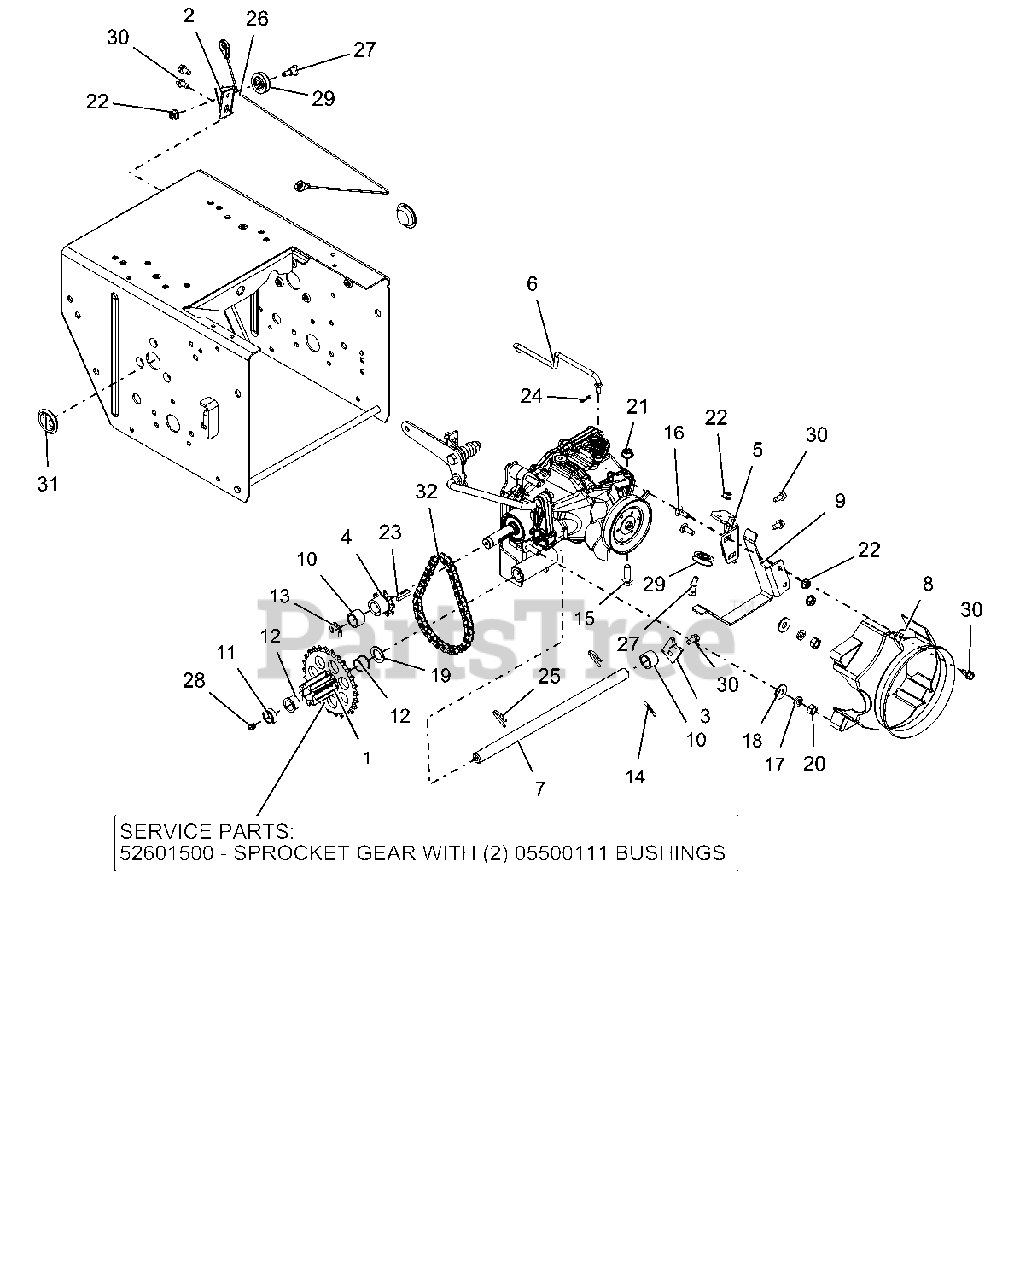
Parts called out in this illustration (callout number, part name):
1	BSHG-FLG .625X.750X.500X.875
1	PINION & SPROCKET
1	PINION & SPROCKET W/BUSHINGS
2	BRACKET, CABLE PULLEY
3	TAB, ANTI ROTATION
4	SPROCKET, PINION 9T W/KEY
5	BRACKET, CLUTCH CABLE
6	ROD, HYDRO BYPASS
7	SHAFT, PINION - HARDENED
8	SHROUD, HYDROGEAR RT-310
9	FINGER, BELT - FLAT
10	SPACER, .635X.880X.611
11	BSHG-SLV, .635X.880X.305
12	BSHG-FLG .625X.750X.500X.875
13	RG-RTNG-EXT .625X.042
14	@PIN-GRV .125X1.00 TP E ALLOY
15	@BLT-HEX .31-18X1.00 GR5 YWZC
16	@BLT-RDHDSQNK .25-20X.75 G5YZ
17	WSHR-LK .312X.097 HVY YWZC
18	@WSHR-FL-STL.38X.875X.083 YWZC
19	WSHR-FL-STL .630X1.005X.062 YZ
20	@NUT-HEX .31-18 YWZC
21	@NUT-LK-TOP-FLG .31-18 YWZC
22	@NUT-LK-TOP-FLG .25-20 YWZC
23	KEY-SQ .188X1.0X.188 SAE 8630
24	PIN-HAIR INT .06X.18X.77
25	PIN, SPRING CLIP
26	CABLE, TRACTION, HYDRO PRO
27	BOLT, SHLDR-.375X.375X.25-20
28	ZERK,FITTING .25X.125 DRIVE IN
29	PULLEY, CABLE
30	SCR-TAP .25-20X.50 HWH TR YWZ
31	PLUG, HOLE - 1.125"
32	CHAIN - #41, 32 PITCHES
